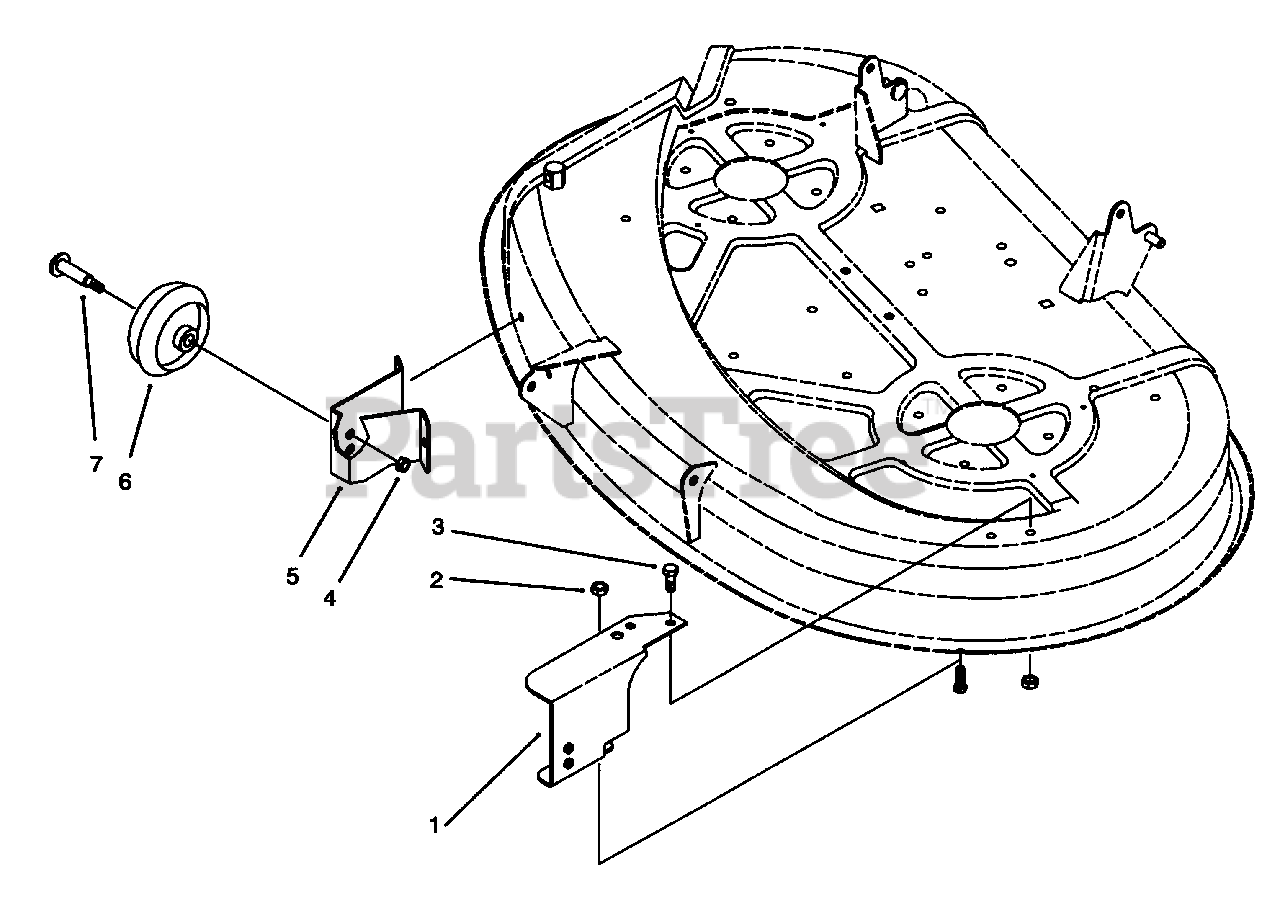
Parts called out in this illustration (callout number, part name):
1	Bracket-Deck Wheel L.H.
2	Nut-Lock
3	Screw-Hex Hd. Cap
4	Nut-Lock
5	Bracket-Deck Wheel R.H.
6	Wheel-Deck
7	Bolt-Wheel
